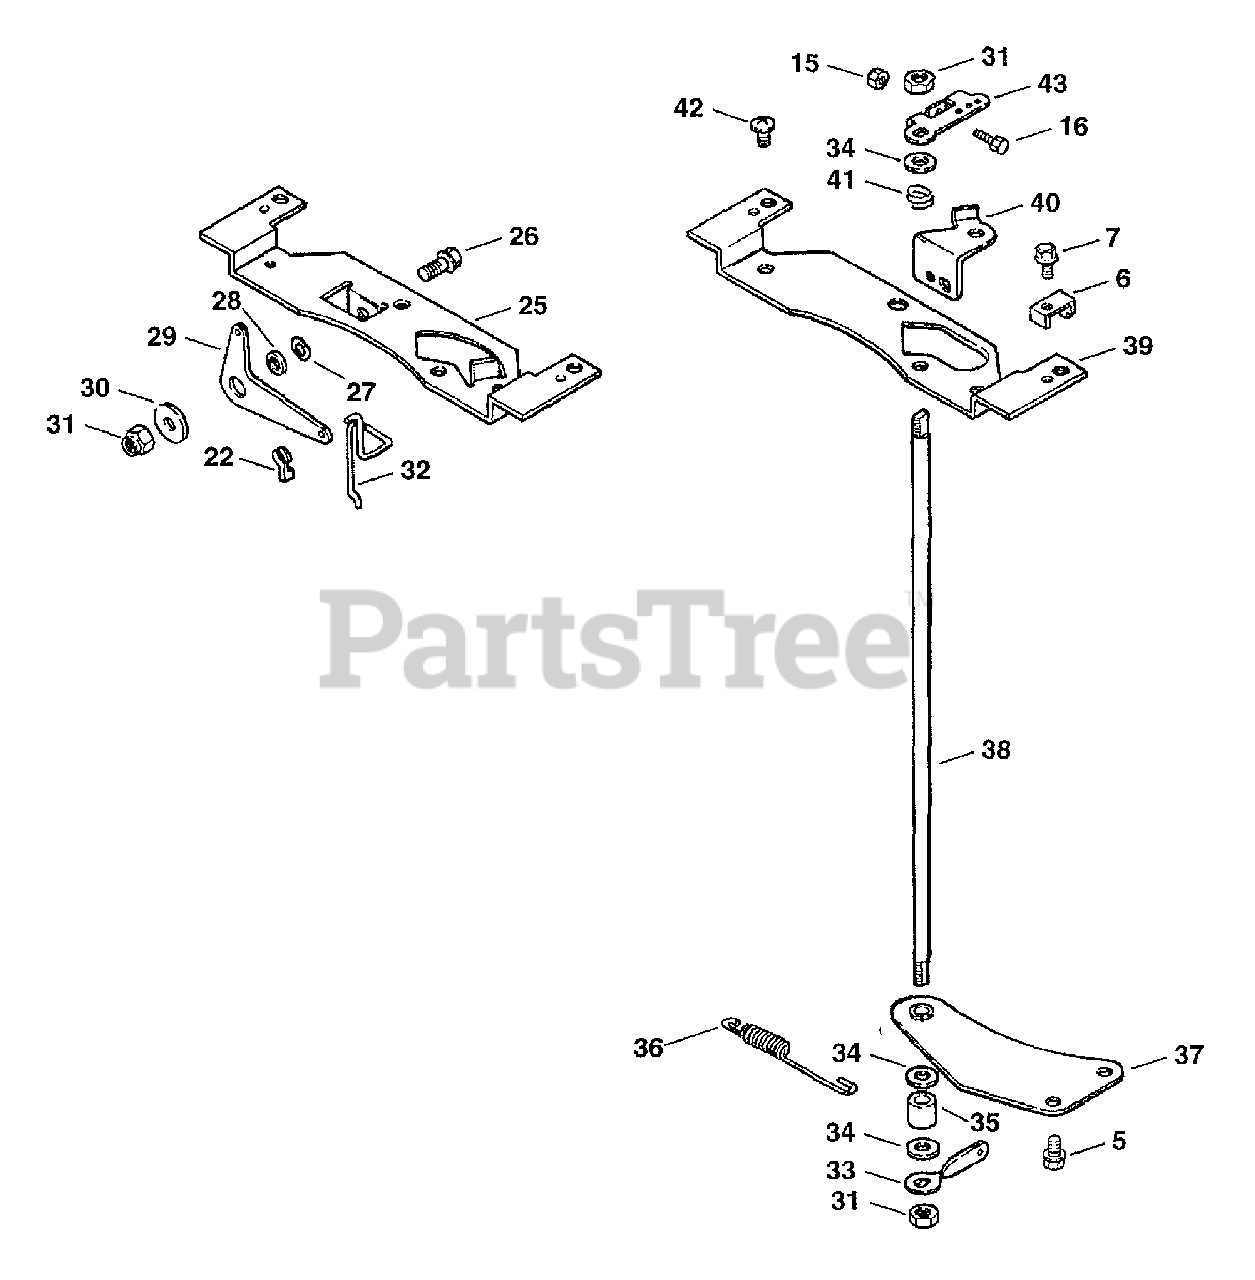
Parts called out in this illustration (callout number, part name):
5	SCREW - USE M-645016
6	CLAMP, CABLE
15	Nut, hex. flange M4x0.7
16	Screw, hex. cap M4x0.7x30
22	BUSHING, THROTTLE LINKAGE
25	BRACKET - USE 24 126 59
26	SCREW - USE M-639016
27	WASHER, SPRING 3/8"
28	SPACER
29	LEVER, CHOKE
30	WASHER, FLAT 1/4"
31	Nut, hex. M6x1.0
32	LINKAGE, CHOKE
33	LEVER, THROTTLE CONTROL
34	WASHER, FLAT 1/4"
36	SPRING, GOVERNOR (CLEAR)
37	BRACKET, THROTTLE SHAFT-USE 24 126 162-S
38	SHAFT, THROTTLE
39	BRACKET - USE 24 126 58
40	BRACKET, CABLE SUPPORT
41	SPRING, THROTTLE SHAFT
42	SCREW, PHL HD 11-16X3/4"
43	LEVER, THROTTLE CONTROL
